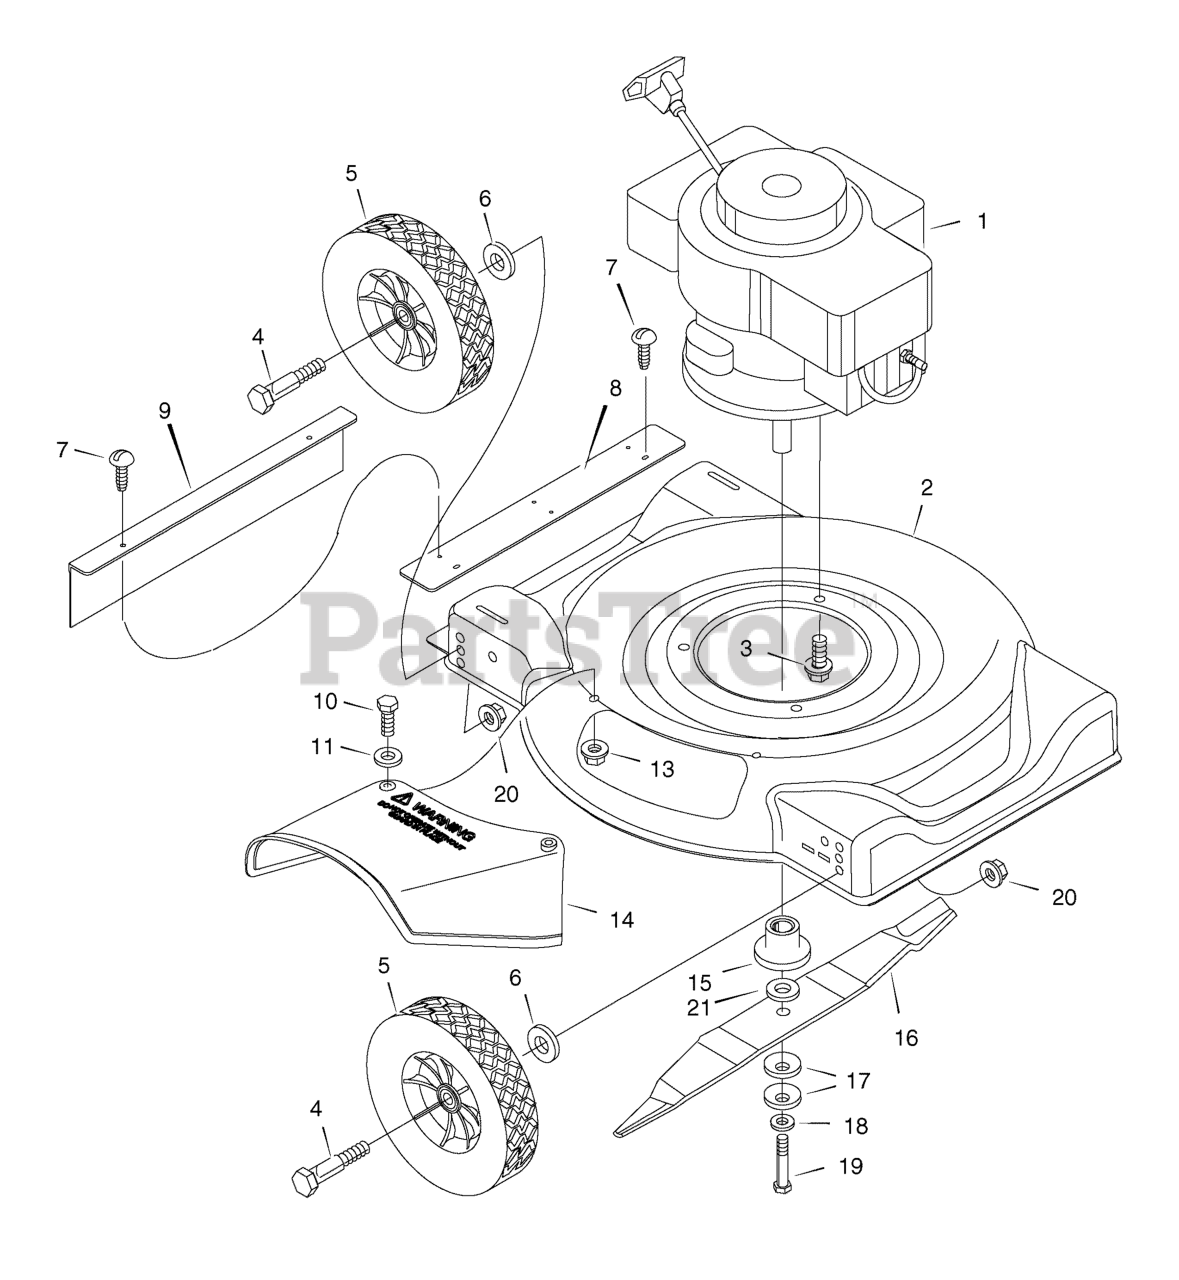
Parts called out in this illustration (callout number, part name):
2	HOUSING, 20"
3	BOLT, HWST, 3/8C X1 BZ
4	BOLT, SHOULDER, 3/8-16 X 2.02
5	WHEEL, 7 X 1.50 DIAMOND-GRAY
6	WASHER, FLAT .390X1.25X.119Z
7	SCREW, HWH SEMS, #10 X .50"
8	EXTENSION, 20" SD, EXPORT
9	GUARD, REAR, 20" PUSH
10	BOLT, HEX, .25-20X0.75 ZINC
11	WASHER, 1/4" PLAIN
13	NUT, HEX LOCK, 1/4-20 BZ
14	DEFLECTOR, CHUTE 20" OPP
15	ADAPTER, BLADE
16	BLADE, 20"
17	WASHER, BLADE
18	WASHER, FLAT, .40.81 16G ZP&O
19	BOLT, HEX, 3/8-24 NF X 1-1/2"
20	NUT, FLANGE LOCK, 3/8-16 NC
21	WASHER, PLAIN, .406 X 2.25
